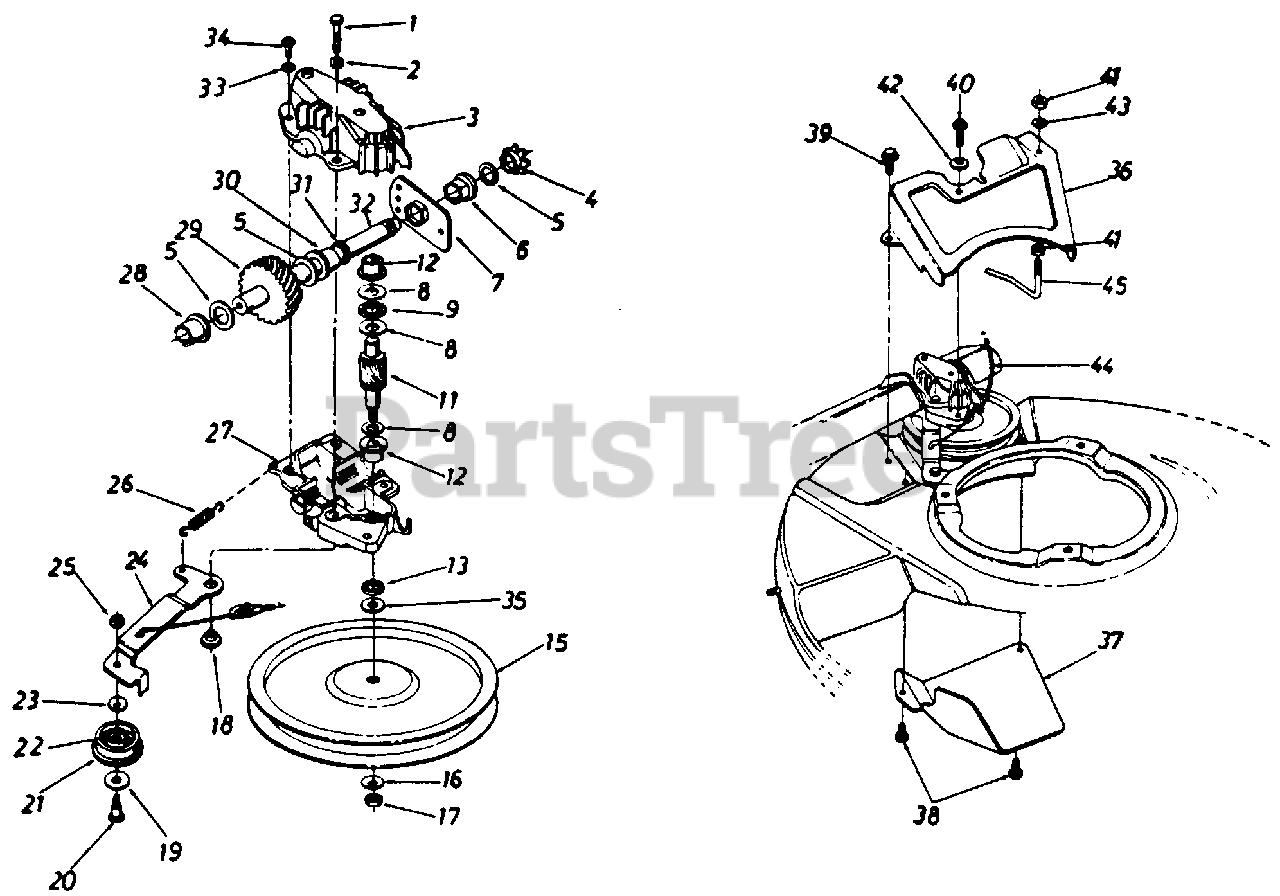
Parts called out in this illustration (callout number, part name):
1	Hex Bolt 1/4-20 x 1.251 Lg. w/Patch
2	L-Wash. 1/4" I.D.
3	Upper Hsg. Halt
4	#48 Sprocket 7 Tooth x 1/2 Pitch
5	Fl-Wash. 5/8" l.D. x .030
6	Hex Flange Brg. 631" l.D.
8	Thrust Wash. .382" l.D. x 70" O D
9	Thrust Bearing .375" l.D. x.812 O.D.
11	11 Tooth Helical Gear
12	Flange Bearing
15	Fl-Pulley 5.06n I.D.
16	Bell-Wash. .265n l.D. x .75"
17	Hex Nut 1/4-28 L.H. Thd.
18	Shld. Spacer .375" Dia. x .170
19	Fl-Wash. .390" l.D. x 1.0"
20	Shld. Bolt .375" Dia. x .40n
21	Fl-ldler Plastic 1.50" Dia.
22	Needle Brg. .375n x .31"
23	Bell-Wash. .265 I.D. x 75
24	Idler Brk't. Ass'y.
25	Hex Patch L-Nut 1/4-28 Thd
26	Extension Spring 1.12" Lg.
27	Lower Hsg. Halt
28	Flange Bearing .56 Dia.
29	33 Tooth Helical Gear
30	Flange Bearing .629 Dia.
31	Oil Seal .625 Dia.
32	Gear Sprocket Shatt
33	L-Wash. #10 I.D.
34	Hex B-Tap Scr. #10 x .62"
35	Hex Washer .26" x .88"
39	Hex AB-Tap Scr. 1/4 x .50" Lg.
40	Hex B-Tap Scr. 1/4 X .62" Lg.
41	Hex Nut 1/4-20 Thd.
42	Bell-Wash. .265" l.D. x 75"
43	L-Wash. 1/4" I.D.
44	S.P. Cable-48" Lg.
45	S.P. Belt Guard
